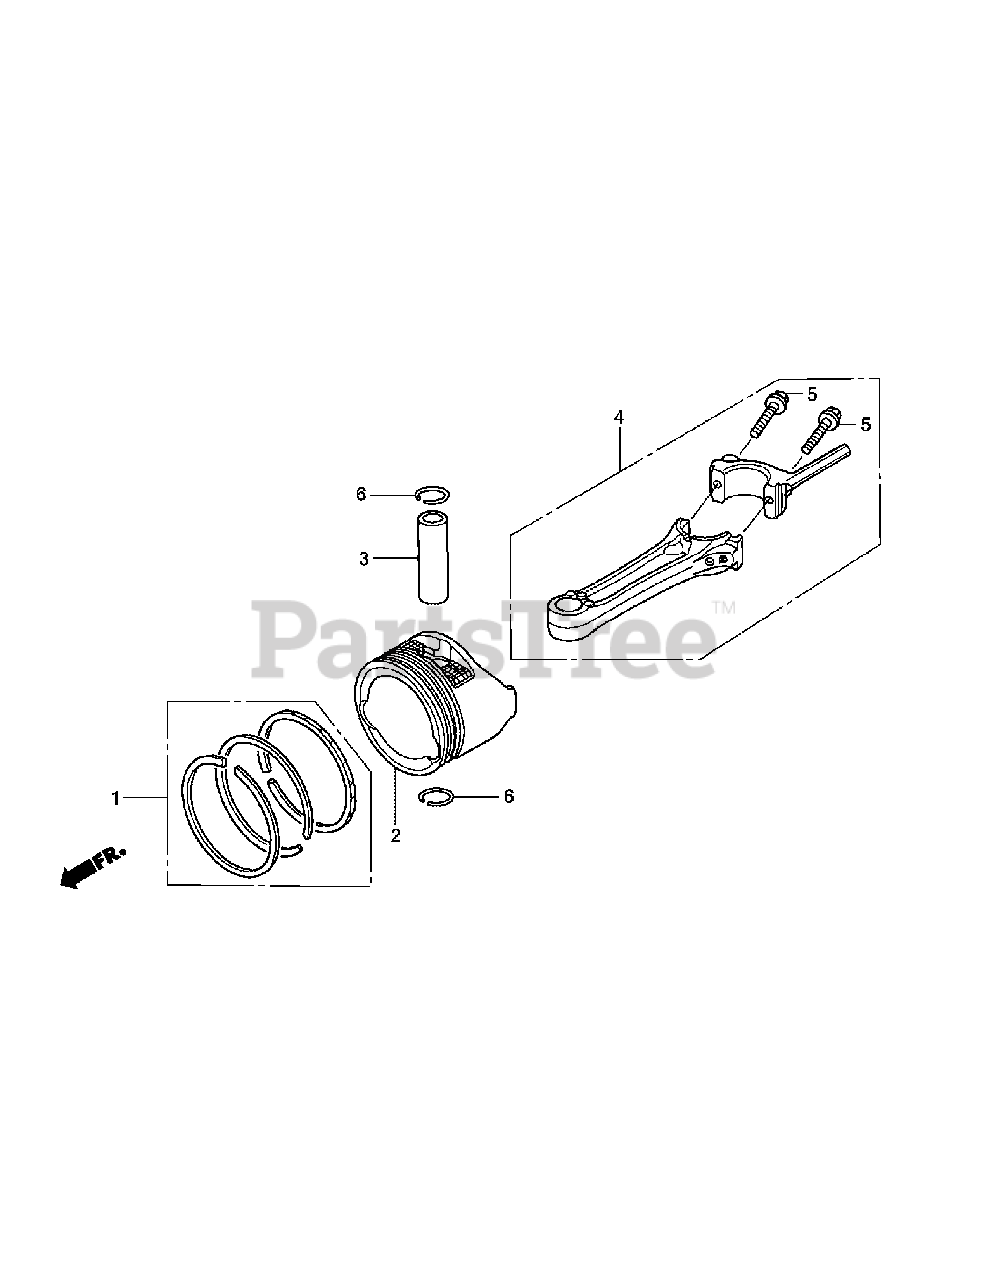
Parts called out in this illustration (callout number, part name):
1	Piston Ring Set
2	Piston
3	Piston Pin
4	Connecting Rod Assembly
5	Connecting Rod Bolt
6	PistonPinClip,13mm
